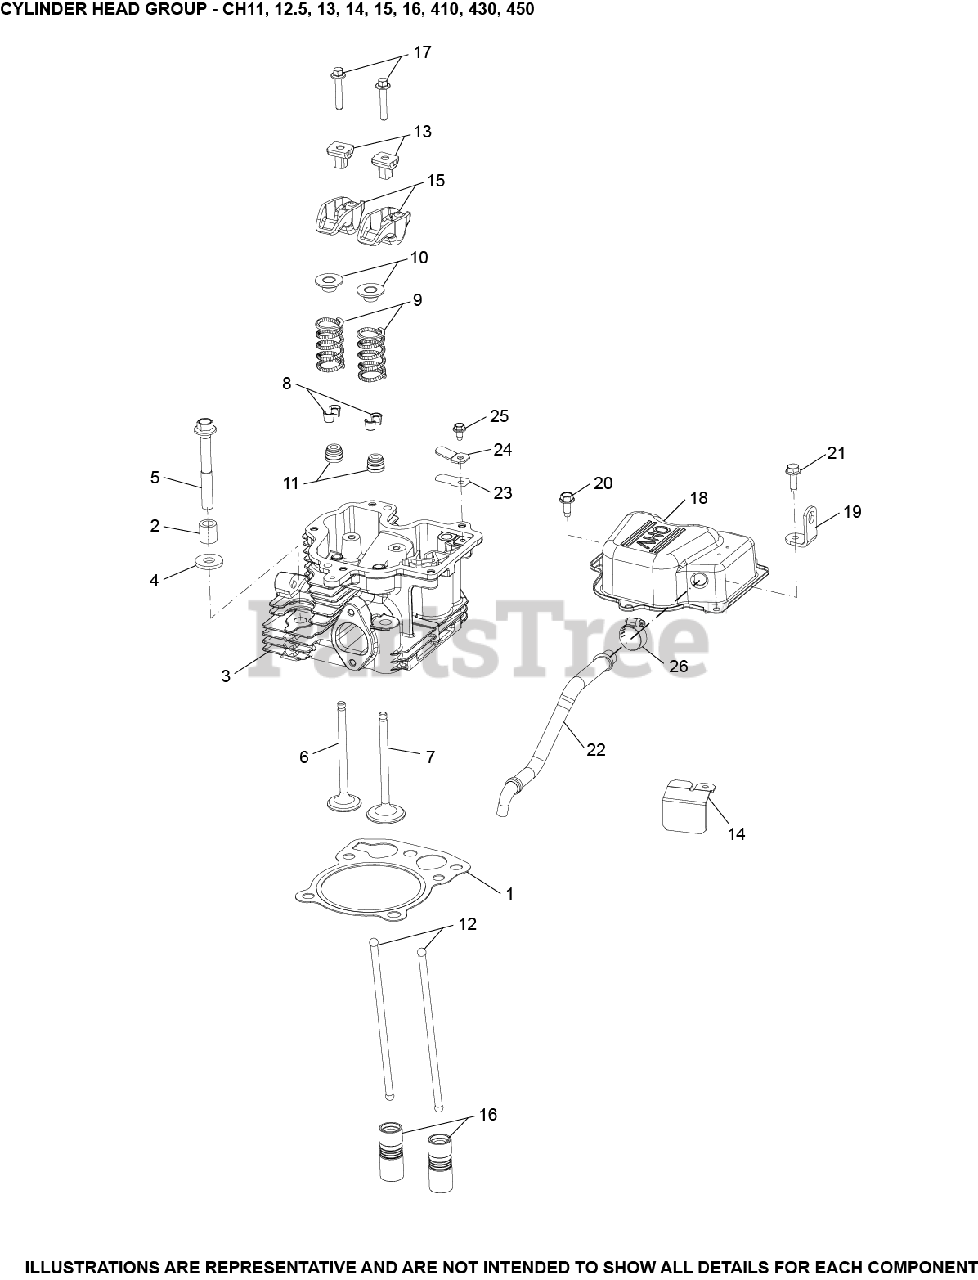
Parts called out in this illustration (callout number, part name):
1	GASKET, CYLINDER HEAD
2	SPACER, HEAD BOLT EXHAUST PORT
3	KIT, HEAD, CYLINDER
4	WASHER, FLAT 13/32"
5	SCREW, CYLINDER HEAD (M10 X 80)
6	VALVE, EXHAUST
6	VALVE, EXHAUST (.25 MM)
7	VALVE, INTAKE
7	VALVE, INTAKE (.25 MM)
8	KIT, RETAINER
9	SPRING, VALVE
10	CAP, VALVE SPRING
11	SEAL, VALVE STEM - (#2503214S)
12	ROD, PUSH
13	PIVOT, ROCKER ARM
14	RETAINER, REED
15	ARM, ROCKER
16	LIFTER, HYDRAULIC VALVE-USE 25 351 10-S
17	SCREW, FLG M6X1.0X34
18	COVER, ROCKER
20	SCREW,FLG THD FRM M6X1.0X16-(#25086397S)
21	SCREW,FLG THD FRM M6X1.0X20-(#25086396S)
22	HOSE, BREATHER
23	REED, BREATHER
24	RETAINER, REED
25	SCREW, FLG THD FRM M5X.8X10
26	CLAMP, HOSE (KM)-USE 25 237 31-S
